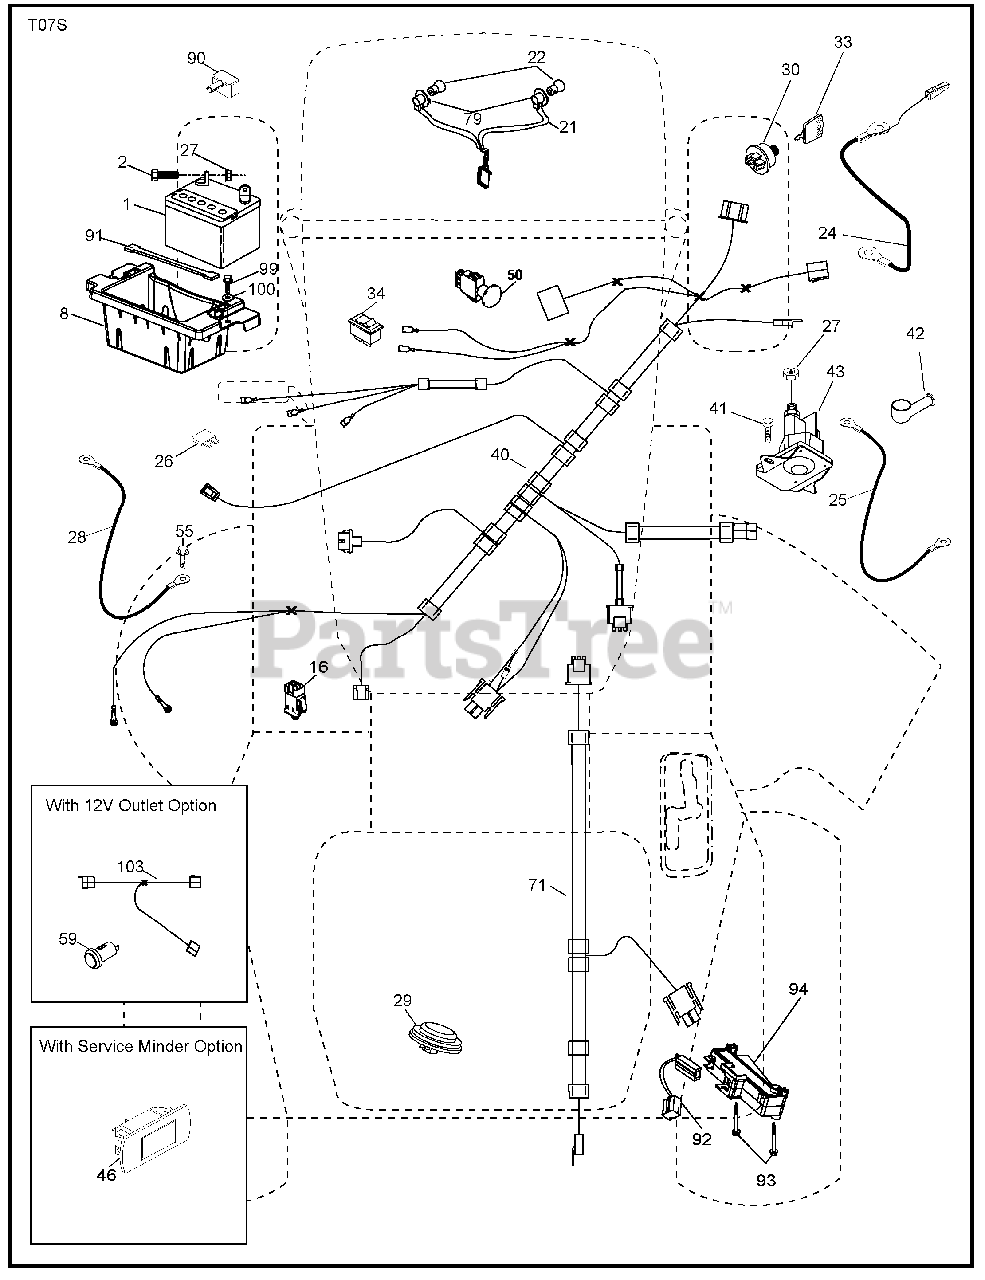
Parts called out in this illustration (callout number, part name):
1	BATTERY.DRY.30.AMP
2	Bolt Hex Hd 1/4-20 unc x 3/4
8	Battery Box
16	Switch Interlock
21	Harness Socket Light
22	Bulb, Light #1156
24	Cable Battery
25	Cable Starter
27	Nut Keps Hex 1/4-20 unc
28	Cable Ground 21" Blk 6 Ga.
29	Switch Seat
30	Switch Ign
33	Key/Chain
34	Switch Light/Reset
40	Harness Ign. Dash
41	Screw Thd Cut 1/4-20 x 1/2
42	Cover Terminal Red
43	Solenoid
46	Gauge Hourmeter
50	Switch PTO
55	Screw Thdrol 5/16-18 x 3/4
59	Outlet 12-Volt
71	Harness Ign Chassis
79	Socket Asm Bulb
90	Cover Terminal Battery
91	Strap Battery
92	Harness Pigtail Reverse Switch
93	Screw Plastite 10-14 X 2.00
94	Module Reverse ROS
99	Screw Hexwsh Thdrol 1/4-20 x 3/4
100	Washer 9/32 x 7/8 x 16 Ga.
103	Harness Pigtail 12 V Outlet
